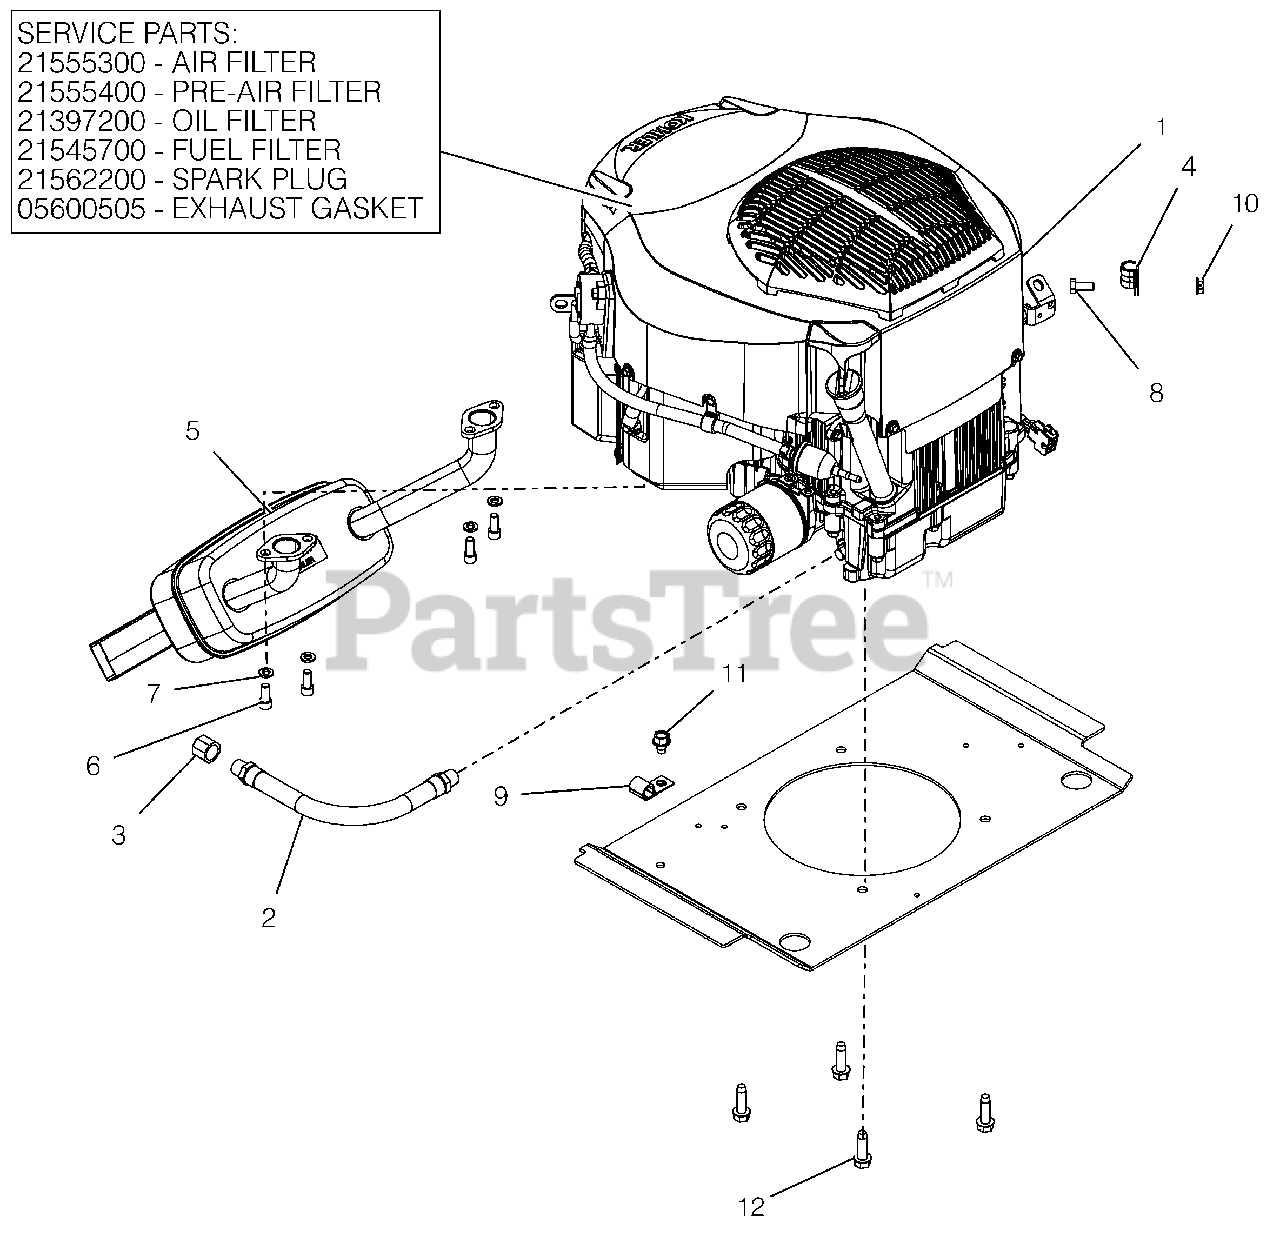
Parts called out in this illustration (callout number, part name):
1	ENGINE-KOHLER TWIN 25 PRO W/SC
1	AIR FILTER, KOHLER
1	PRE CLEANER, KOHLER
1	FILTER, OIL - KOH CV20
1	FILTER-FUEL KOHLER COURAGE PRO
1	PLUG, SPARK (RFI)
1	GASKET, MUFFLER KOHLER TWIN
2	HOSE,HYD .38-11-0K M6NO-M6N0
3	PIPE CAP 3/8 NPT FEMALE
4	CLAMP, CUSHIONED STEEL
5	MUFFLER, KOHLER
6	SCR-CAP .31-18X.75 S/HD
7	@WSHR-LK .31X.078 REG YWZC
8	@BLT-HEX .31-18X.75 GR5 YWZC
10	@NUT-LK-CTR-FLG .31-18 YZ GR F
11	@SCR-TAP .38-16X.50 HWH TR YWZ
12	@SCR-TAP .38-16X1.25 HWH TR YZ
